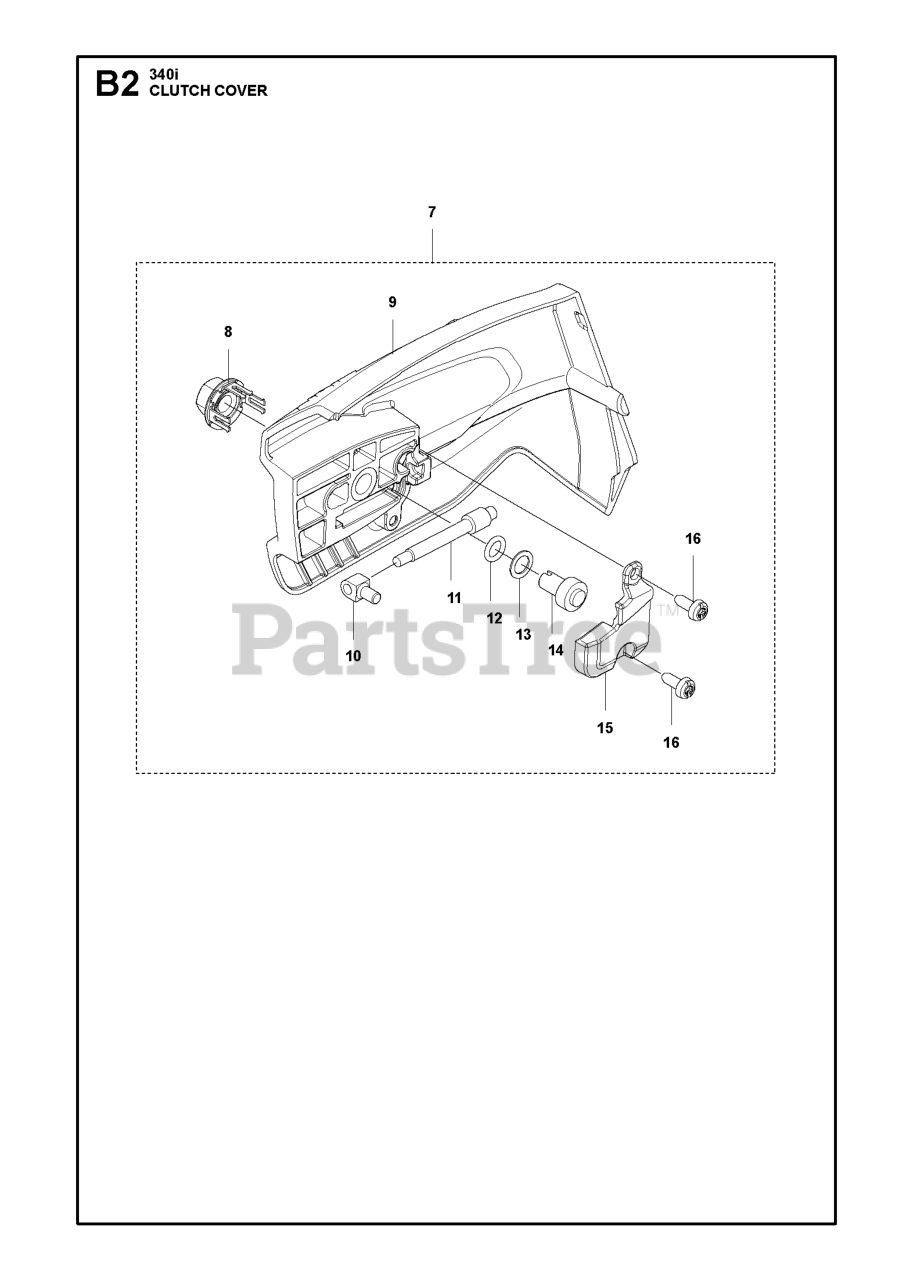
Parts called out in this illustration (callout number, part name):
7	CLUTCH COVER
8	NUT RETAINER ASSY
9	CLUTCH COVER T540I XP
10	PIN BAR ADJUSTING
14	WORM WHEEL LEFT HAND TEETH
15	COVER LID
